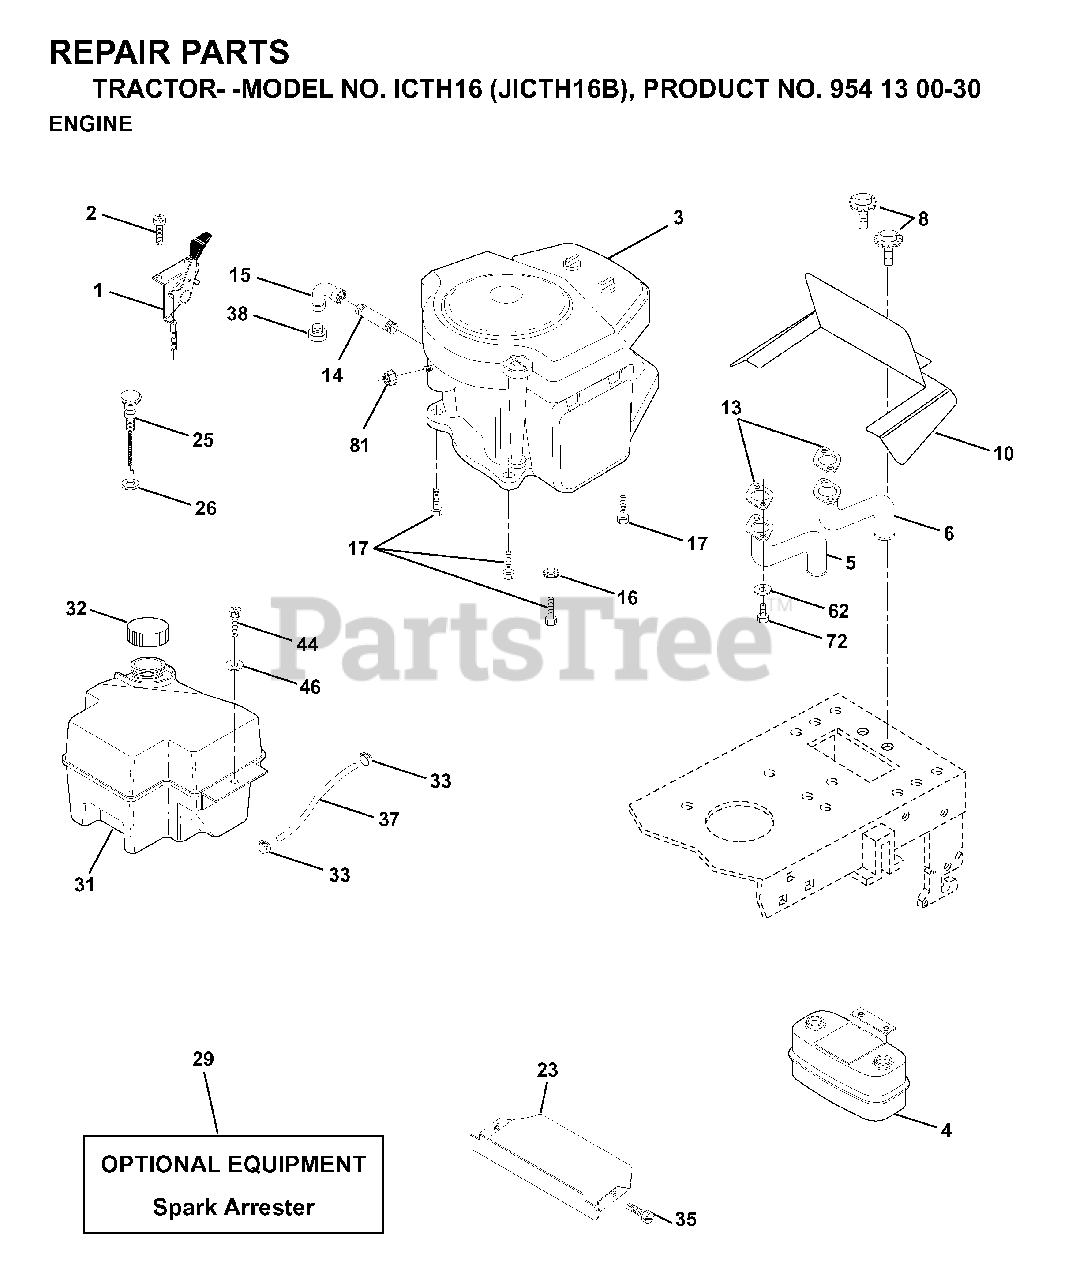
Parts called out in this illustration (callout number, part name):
1	CONTROL THROTTLE 36"
2	SCREW LT
4	MUFFLER.TWIN.CYL.LOW.TONE
5	TUBE MANIFOLD LH
6	EXHAUST TUBE RH
8	BOLT HEX WASHER HD 5/16-18
10	SHIELD.BROWNING.B&S
13	GASKET.MUFFLER
14	PIPE NIPPLE LT
15	ELBOW
16	LOCKWASHER
17	SCREW LT
23	PROTECTOR
25	CONTROL, CHOKE
26	NUT KEPS 3/8 - 24 UNF
29	ARRESTER SPARK (OPTIONAL)
31	FUEL TANK
32	FUEL CAP
33	HOSE CLAMP
35	SCREW
37	LINE.FUEL.20
44	SCREW HEX CRT
62	LOCKWASHER
72	SCREW
81	NUT FLANGE 1/4-20 STARTER NUT
